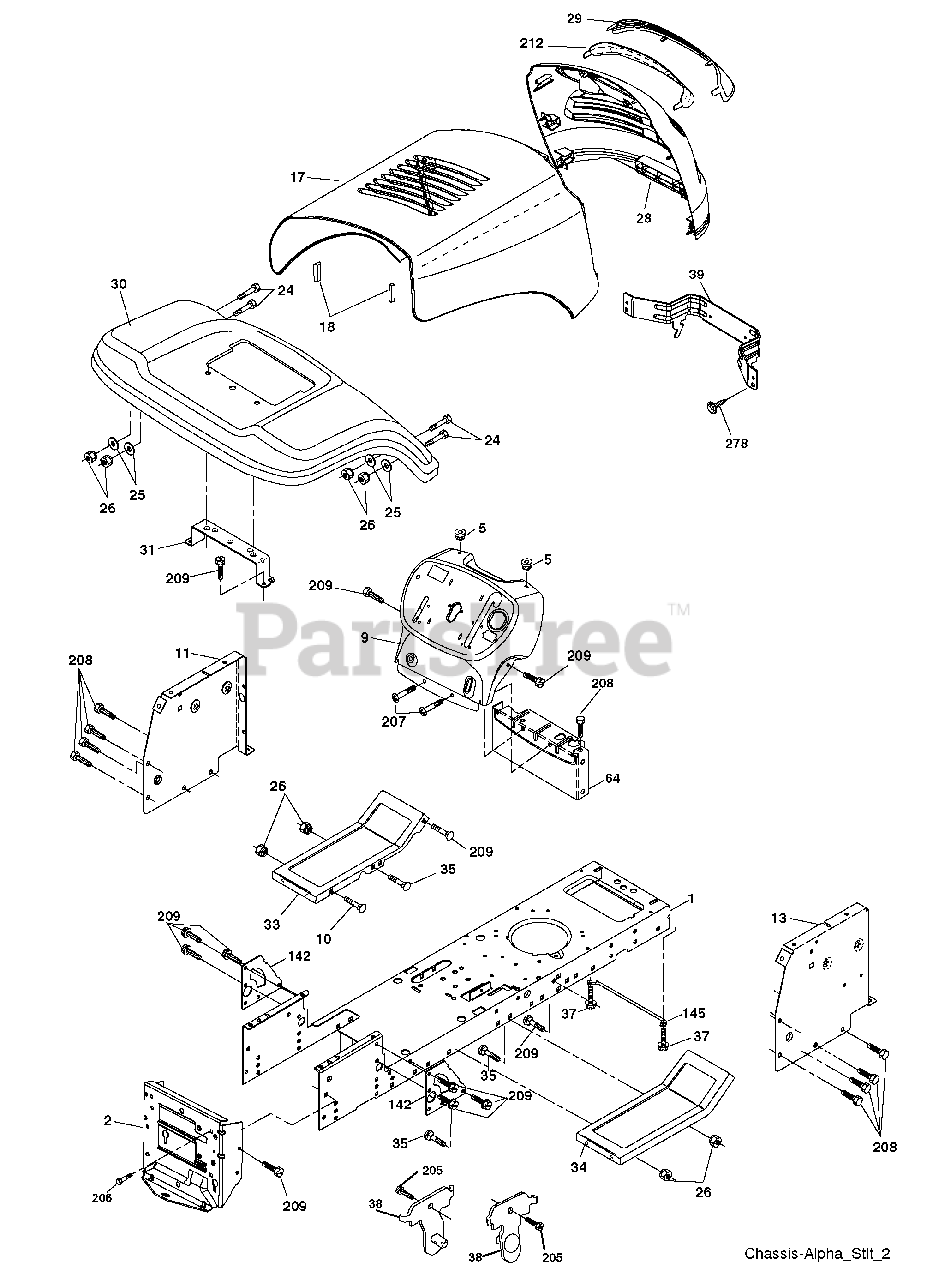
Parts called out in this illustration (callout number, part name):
1	Chassis
2	Drawbar, Stretch
5	Bumper, Hood/Dash
9	Dash
10	Bolt, Carriage 3/8-16 x 1
11	Panel Dash LH
13	Panel Slkscr Dash RH
17	Hood
18	Bumper Hood
24	Bolt Fin Hex 3/8-16 unc x 1 Gr. 5
25	Washer 13/32 x 13/16 x 12 Ga.
26	Nut Lock Hex w/Ins 3/8-16 unc
28	Grille/Lens Asm.
29	Lens Grille Bar
30	Fender
31	Bracket Fender Repl 109873X
33	Footrest Pnt LH
34	Footrest Pnt RH
35	Bolt Rdhd Sht Sqnk 3/8-16 x 3/4
37	Screw Thdrol 5/16-18 x 1/2 TYT
38	Bracket Asm. Pivot Mower
39	Bracket Pivot
64	Dash Lower
142	Plate Reinforcement
145	Rod Pivot Chassis/Hood
205	Screw Thdrol 3/8-16 x 1/2
206	Bolt Shoulder 5/16-18
207	Screw 5/16-18 x 1/2
208	Screw Thdrol 3/8-16 x 1/2
209	Screw Hex Wsh Thdrol 3/8-16
212	Insert Lens Reflect
278	Screw 10 x 3/4 Single Lead Hex
278	Plug Button Blk 359 Dia Choke
278	Plug Dome Plastic
